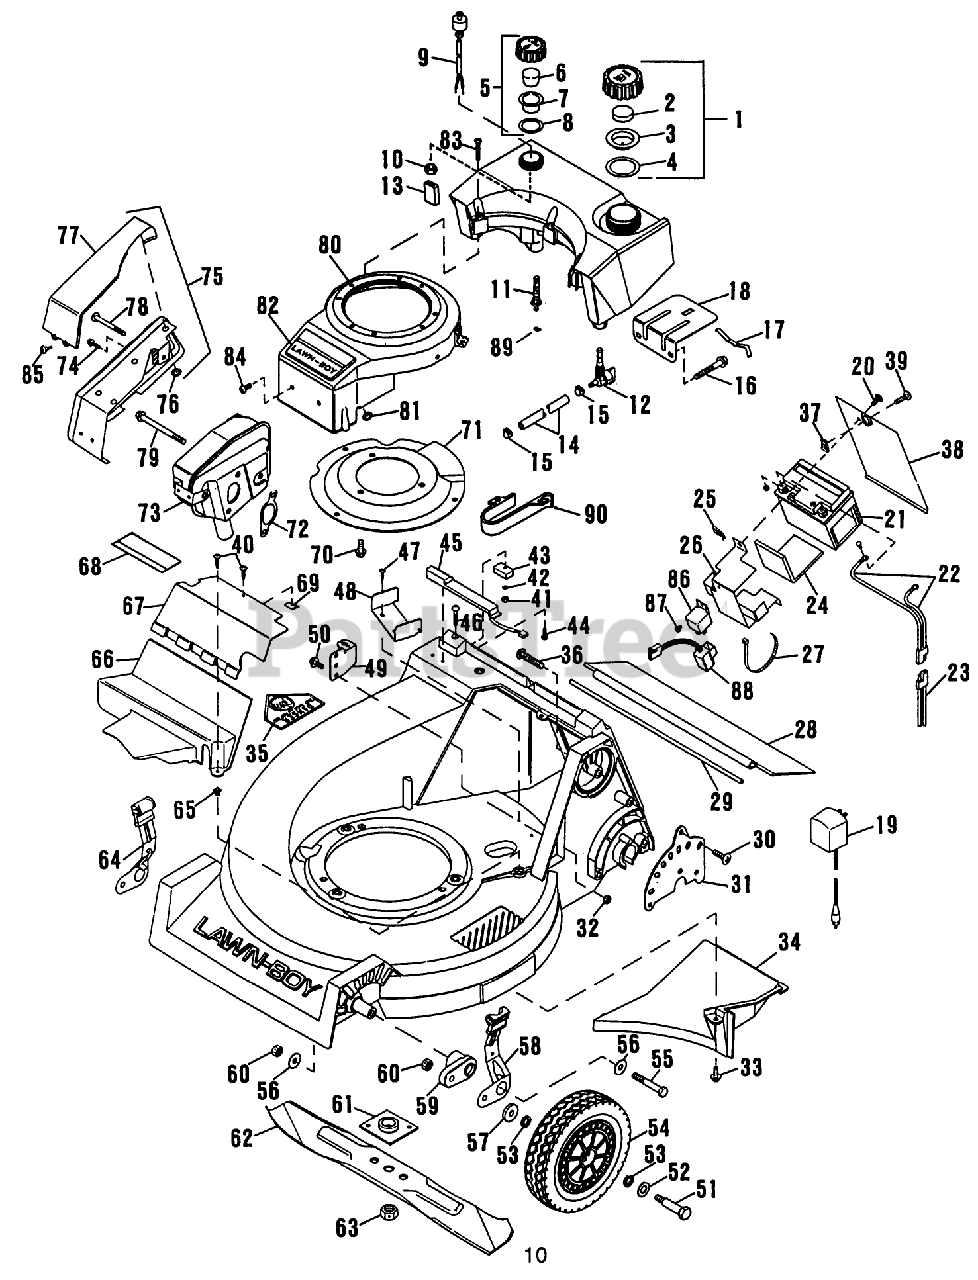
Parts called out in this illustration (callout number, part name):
1	CAP AY - FUEL M
2	BAFFLE - FOAM SM
4	GASKET-FUELCAP SM
5	CAP AY. OIL M
6	FILTER S
12	DISC/LB SER.BUL.#6
14	GAS LINE SM
15	HOSE CLAMP SM
16	SCREW-HEX W.H. SM
17	SPRING
18	DISC. LB SER.BUL.#6
25	SPEED NUT ARDEN
30	SCREW-BHTF
31	PLATE HGT CMS
32	LOCKNUT E
34	CHUTE BAFFLE NYL
37	SPEED NUT LARSON
38	DOOR-ACCESS ELECT.
39	SCREW-CROSS RECESS
40	SCREW S
45	SWITCH AY DELTA
52	SPACER
53	WASHER
54	WHEEL&TIRE 8" TRI
56	WASHER-PLAIN
57	WASHER
58	KNOB & SPRING CMS
60	NUT-JAM, LOCKING
61	PLATE AND COLLAR ASM
63	NUT-BLADE
64	KNOB & SPRING CMS
65	NUT-CLIP
69	NUT-SPEED
71	PLATE SM
72	GASKET - EXH SM
74	SCREW S
75	MUFFLER GUARD AY
76	NUT-PUSH
77	COVER MUFFLER CP
78	SCREW SM
79	SCREW-SEMS
81	NUT-PUSH
83	DISC.LB SER.BUL.#6
85	SCREW SM
